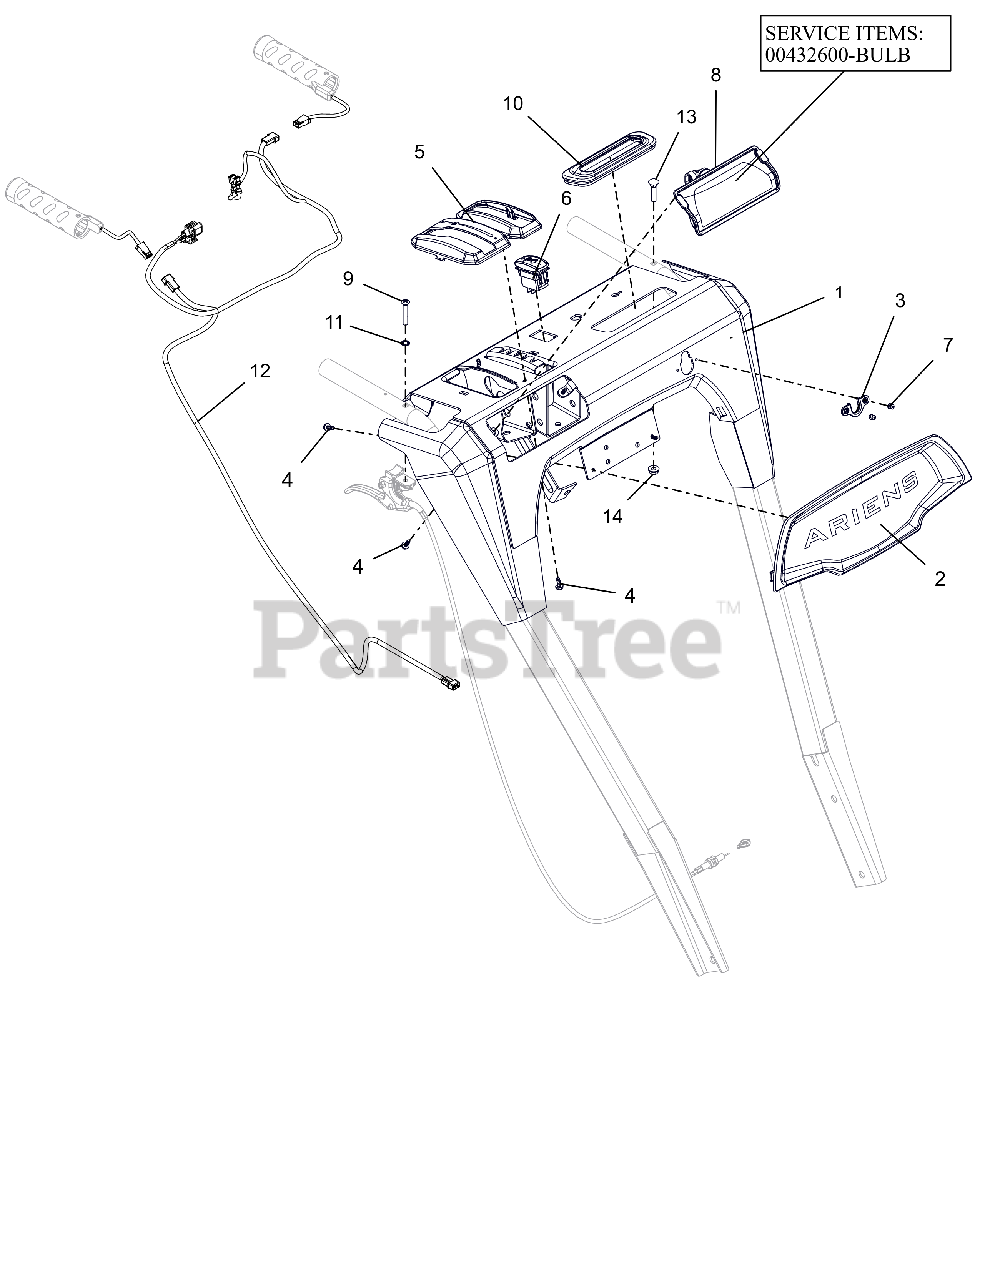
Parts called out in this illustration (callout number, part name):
1	WELDMENT,DASH,LRG,QT2 HYDRO
2	BEZEL, DASH - ARIENS LG DASH
3	GROMMET, CABLE, QUICK TURN 2
4	SCR, PLASTIC #10X.50
5	BEZEL, SHIFT - HYDRO SNOW
6	SWITCH,ROCKER SPST-ON/OFF
7	RVT-POP #43 .125X.313 STL ZINC
8	HEADLIGHT ASY, HALO 20W 2SHOT
8	BULB, LIGHT-HALOGEN 20W
9	SCR,OVAL .25-20X1.50 ZCC
10	GROMMET, BOOT, QUICK TURN
11	WSHR-LK-INT .250 TH TYA
12	HARNESS,LIGHT&WARMER - EFI
13	BLT-RDHDXLSQNK.25-20X1.25 G5ZC
14	NUT-LK-CTR-FLG .25-20 ZC120
